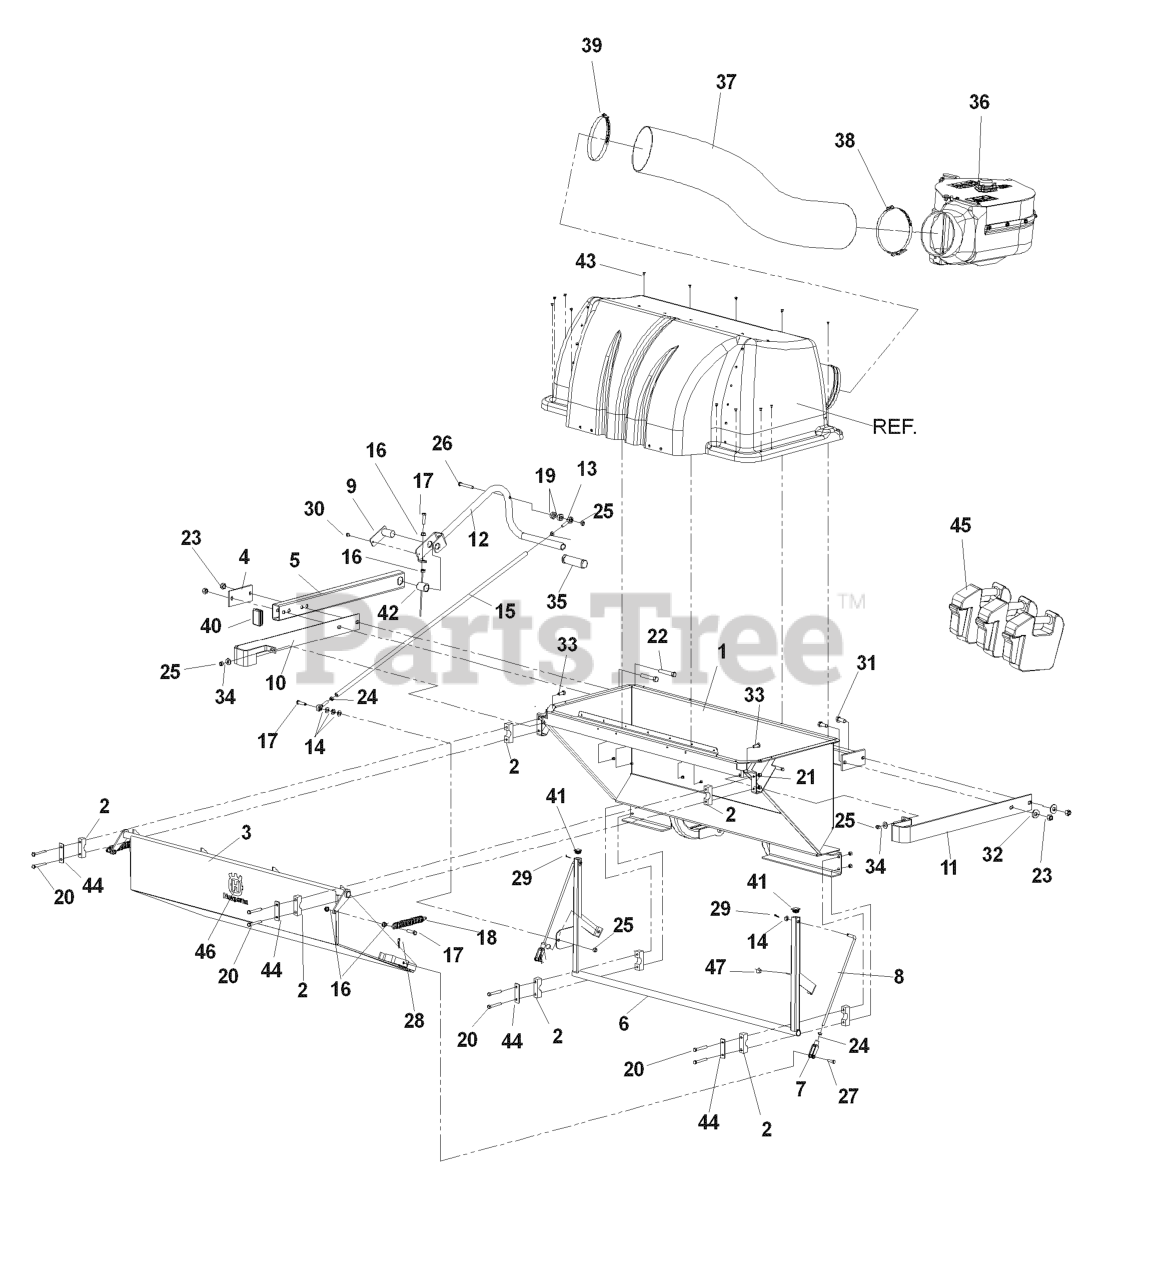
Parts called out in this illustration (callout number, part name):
1	WELDMENT - HOPPER
2	PILLOW BLOCK
3	WELDMENT - DOOR
4	PLATE - BACKING
5	TUBE - SUPPORT, HANDLE
6	WELDMENT - BELL CRANK
7	YOKE-3/8-24 PLTD
8	ROD.DOOR.COLECTION
9	WELDMENT - PIN, PIVOT
10	GUARD - L.H.
11	GUARD - R.H.
12	WELDMENT, HANDLE
13	ROD END - 3/8-24 RH
14	WASHER 3/8 SAE FLAT
15	TUBE - THREADED
16	NUT 3/8C WHIZ
17	HCS 3/8C X 1 1/2
18	SPRING BAGGER
20	BOLT 5/16C X 2 1/2
21	NUT 5/16 NYLOC
22	SCREW, 1/2C X 3 HEX CAP
23	NUT 1/2-13 HEX NYLOC ZD
24	NUT 3/8-24 JAM
25	NUT 3/8-16 NYLOC
26	HEX SCREW 3/8-20 X 2.75
27	PIN CLEVIS, 3/8 X 1 1/4
28	HAIRPIN #2
29	RP_COTTER PIN 1/8 X 3/4
30	HWST 1/4C X 3/8
31	HCS 1/2-13 X 1-1/4
32	WASH USS FLAT 1/2
33	HCS 3/8-16X1.GRD.5.ZD
34	WASHER 3/8 FLAT
35	IMPELLER KIT, 3.5/5HP
36	BLOWER ASSEMBLY
37	HOSE 7 X 58 CLEAR
38	OVER CTR BAND
39	HOSE CLAMP 4-1/8 TO 7"
40	PLUG - RETANGULAR TUBING
41	PLUG - SQUARE TUBE
42	BUSHING - BRONZE, 1.0"
43	RIVERT, 3/16, STAVEX
44	REINFORCEMENT BAR
45	FRT WEIGHT CAST PZ DFS
46	DECAL, CROWN H 5-1/4 SILVER
47	GROMMET, BUMPER
